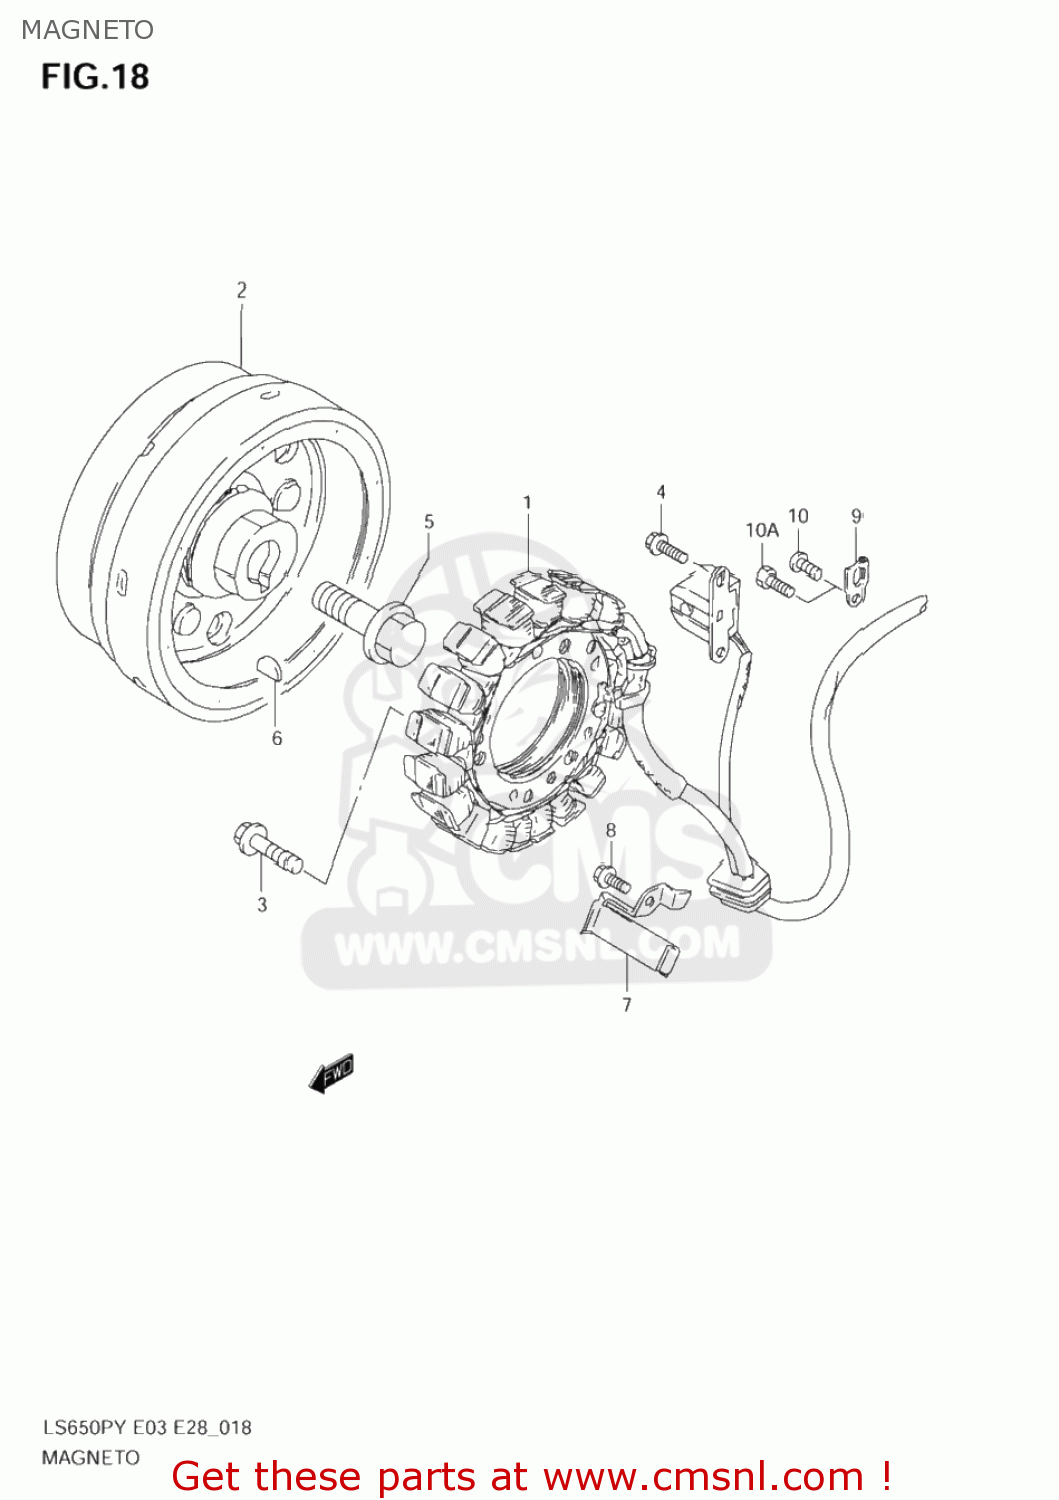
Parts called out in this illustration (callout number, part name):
1	STATOR ASSEMBLY
2	ROTOR ASSY
3	SCREW
4	BOLT
5	BOLT(14X43)
6	KEY
7	CLAMP,MAGNETO LEAD WIRE NO.1
8	BOLT
9	CLAMP,GENERATOR LEAD WIRE
10	SCREW
10A	BOLT(5X10)
